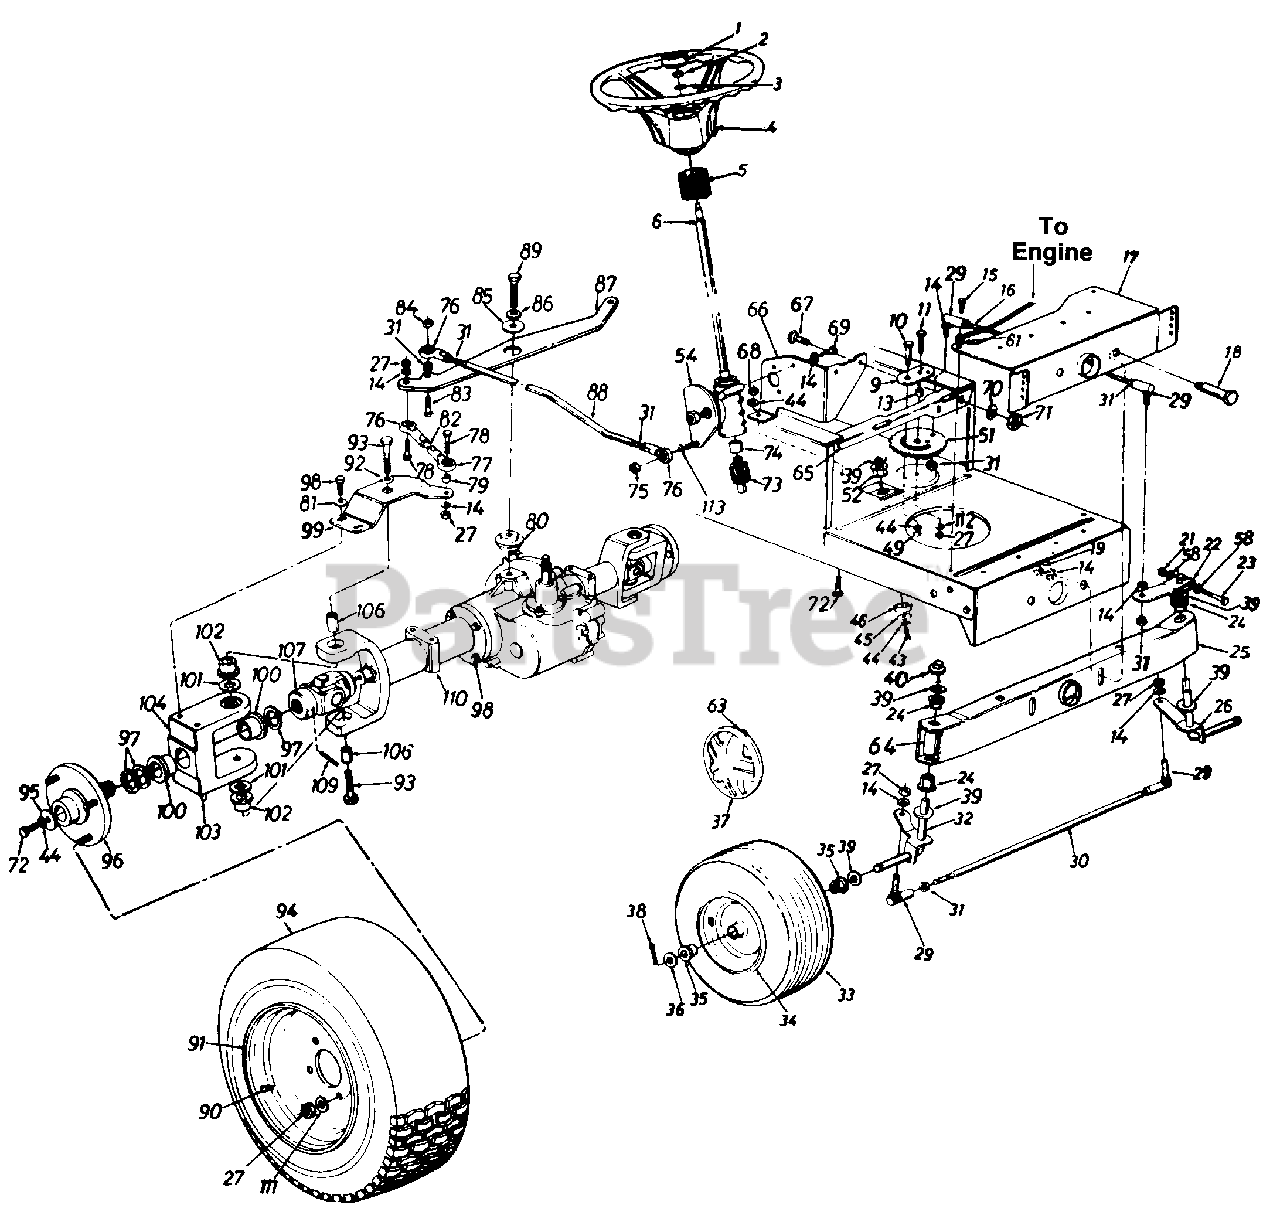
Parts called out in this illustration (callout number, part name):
1	Steering Wheel Cap
2	Hex L-Nut 5/16-24 Thd.
3	Belleville Wash. .845" l.D.
4	Steering Wheel
5	Steering Bellow
6	Steering Shaft Ass'y.
9	Retainer Plate
10	Shoulder Bolt .437" Dia. x .35" Lg. 5/16-18 Thd.
11	Hex Bolt 3/8-24 x 1.0" Lg. (Grade 5)
13	Spacer .380" I.D. x .625" O.D. x .227"
14	L-Wash. 3/8" I.D.
15	Hex Wash. Hd. Self-Tap Scr.
16	Steering Drag Link
17	Front Pivot Brkt.
18	Shoulder Bolt .498" Dia. x 2.04" Lg. 3/8-16 Thd.
19	Hex Nut 3/8-16 Thd.
21	Hex Cent. L-Nut 5/16-24 Thd.
22	Steering Arm Front Axle
23	Hex Bolt 5/16-24 x 2.00" Lg. (Grade 5)
24	Hex Flg. Brg. .634" l.D.
26	Front Axle Ass'y.-L.H.
27	Hex Nut 3/8-24 Thd.
29	Ball Joint 3/8-24 Thd.
31	Hex Jam Nut 3/8-24 Thd.
32	Front Axle Ass'y.-R.H.
33	Wheel Ass'y. Comp.
34	Front Wheel Rim Only
35	Flange Bearing
36	Fl-Wash. .635" l.D. x 1.59" O.D.
37	Front Hub Cap
38	Cotter Pin 1/8" Dia. x 1.25n Lg.1
39	Fl-Wash. .640" I.D. x .24" O.D.
40	Spring Roll Pin
43	Hex L-Bolt 5/16-18 x .62"
44	L-Wash. 5/16" I.D.
45	Fl-Wash. .33" I.D. x 1.25" O.D.
46	Spacer (Plastic)
49	Hex Nut 5/16-18 Thd.
51	Steering Gear Segment
52	Hex Flg. Brg. .634 I.D.
54	Steering Ass'y. Comp.
58	Wave Wash. .32" I.D. x .62"
61	Ext. L-Wash. 5/16" I.D.
63	Spring Clip
64	Plastic Tube
65	Horizontal Cross Bracket
66	Vertical Mounting Bracket
67	Hex Bolt 1/4-28 x .75" Lg.
68	Hex Nut 5/16-24 Thd.
69	Hex Bolt 3/8-16 x 1.0n Lg.
70	Bell-Wash. .265" l.D. x ,75n
71	Hex Nut 1/4-28 Thd.
72	Hex Bolt 5/16-24 x .75" Lg.
73	Pinion Shaft
74	Steering Shaft Splined Coupler
75	Hex L-Nut 3/8-24 Thd.
76	Rod End 3/8-24 Thd.-R.H.
77	Rod End 3/8-24 Thd.-L.H.
78	Hex Bolt 3/8-24 x 1.5" Lg. (Gr. 5)
79	Spacer .38" I.D. x .625"
80	Shld. Spacer .51" I.D.
81	Bell-Wash. .38" I.D. x .88"
83	Hex Bolt 3/8-24 x 1.25" Lg.
84	Hex Patch L-Nut 3/8-24 Thd.
85	Fl-Wash. .531" I.D. x 1.75"
86	Bell-Wash. .505" I.D. x 1.0"
89	Hex Bolt 1/2-13 x 1.5 Lg. (Gr. 5)
90	Air Valve
93	Hex Bolt 1/2-20 x 1.75" Lg. (Gr. 5)
95	Fl-Wash. .33" I.D. x 1.25"
96	Wheel Flange Ass'y.
97	Fl-Wash. 1.0" x 1.56"
98	Hex Bolt 3/8-24 x 1.25" Lg.
101	Fl-Wash. .76" l.D. x 1.5
102	Flange Brg. 3/4" I.D.
103	Grease Fitting
104	Wheel Brg. Housing
106	Pivot Sleeve
109	Grooved Roll Pin 1.0" Lg.
110	Axle Horn Ass'y.
111	Bell-Wash. ,38n l.D. x .88n
112	Bell-Wash. ,39n l.D. x 1.38"
113	Fl-Wash. ,385n l.D. x .62"
